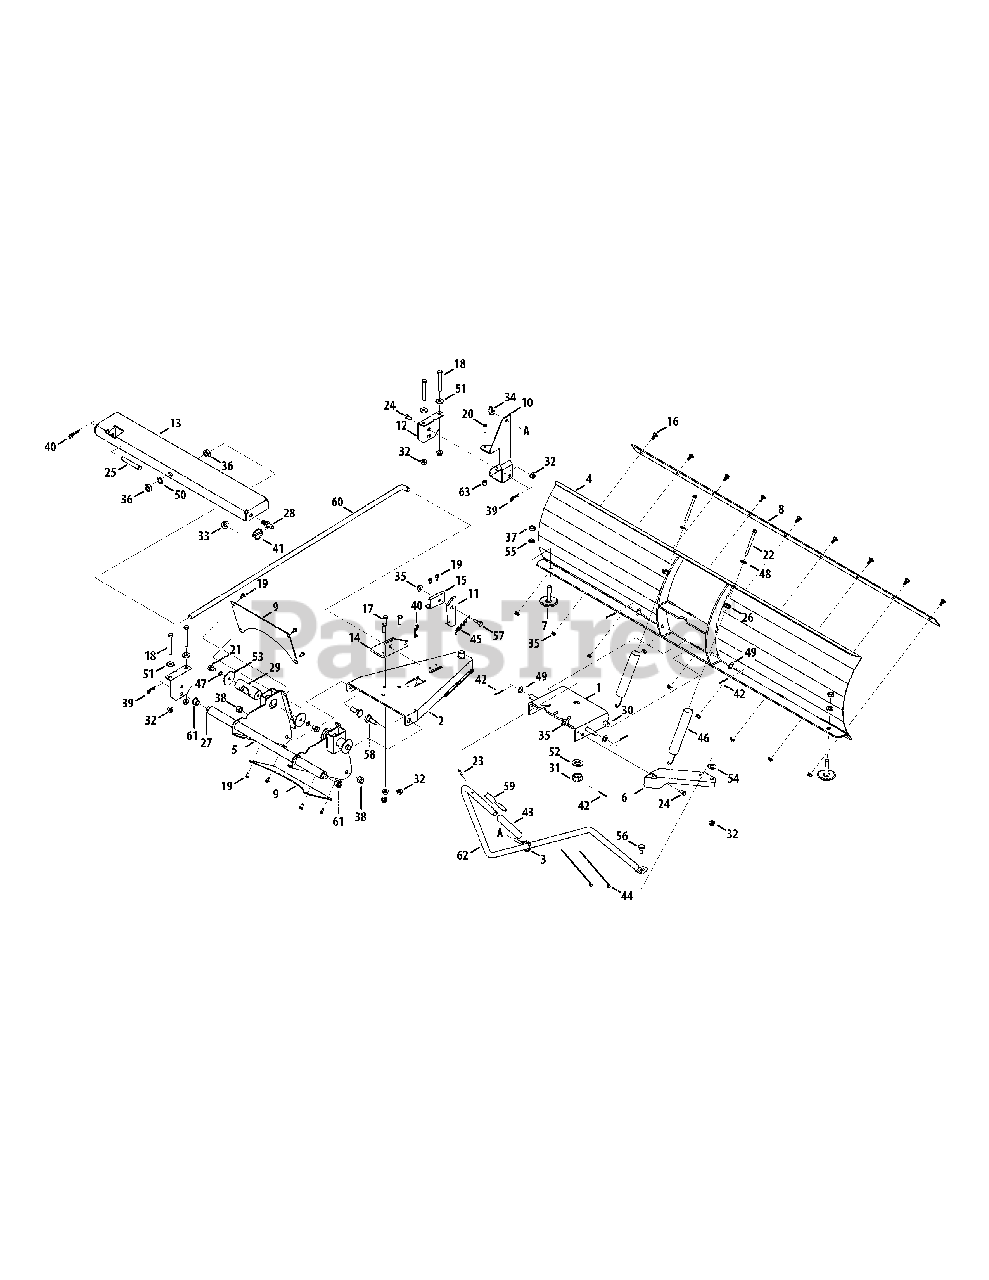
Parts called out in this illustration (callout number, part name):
1	Blade Pivot Assembly
2	Blade Frame Assembly
3	Eyebolt Assembly
4	Blade Assembly
5	Brace Bracket Assembly
6	RH Blade Adjust Arm
8	Blade Scraper Plate
10	Handle Mount Bracket
11	Blade Lock Plate
12	Mount Bracket
13	Blade Lift Bracket
14	Front Lift Bracket
15	Pivot Bracket
16	Carriage Bolt, 5/16-18 x .750
17	Hex Screw, 3/8-16 x 1.00
18	Hex Screw, 3/8-16 x 3.00
19	Hex Washer Screw, 1/4-20 x .500
20	Hex Washer Screw, 1/4-20 x 1.000
21	Hex Washer Screw, 3/8-16 x .625
22	Hex Screw, 5/16-18 x 3.50
23	Machine Screw, #10-24 x 1.375
24	SCREW 5/16-18 x .75 GR5
25	Clevis Pin, .50 x 3.25
26	Spring Insert
27	Rod, .50 x 22.65
28	Deck Lock Pin, .500
29	Pivot Pin, 1.250
30	Rod, .50 x 10.428
31	Slotted Nut, 3/4-16
32	Flange Lock Nut, 3/8-16
33	Flange Lock Nut, 1/2-13
34	Wing Nut, 5/16-18
35	HEX FLANGE NUT
36	Jam Nut, 5/8-11
37	Jam Nut, 1/2-13
38	Hex Lock Nut, 1/2-13
39	Click Pin, .092 x 1.64
40	Cotter Pin, .125 x 1.75
41	Lynch Pin, .1875
42	Cotter Pin, 1/8 x 1.25
43	Foam Grip
44	Cable Tie, 3/16 x 7.4
45	Extension Spring, .38 x 3.25
46	Extension Spring, 1.25 x 6.7
47	Lock Washer, 3/8
48	Flat Washer, .349 x .879 x .063
49	Flat Washer, .53 x .93 x .050
50	Lock Washer, 5/8
51	Flat Washer, .385 x 1.0 x .135
52	Flat Washer, .760 x 1.50 x .120
53	Flat Washer, .38 x 2.00 x .12
54	Flat Washer, .570 x 1.120 x .062
55	Lock Washer, 1/2
56	SHOULDER SCREW .498 DIA x .340
57	Shoulder Screw, 5/16-18 x .405 x .435
58	Shoulder Screw, 1/2-13 x .625 x .36
59	Blade Release Cable
61	Flange Bearing, .503 x .75
62	Blade Adjust Handle
63	Spacer, .258 x .50 x .50
